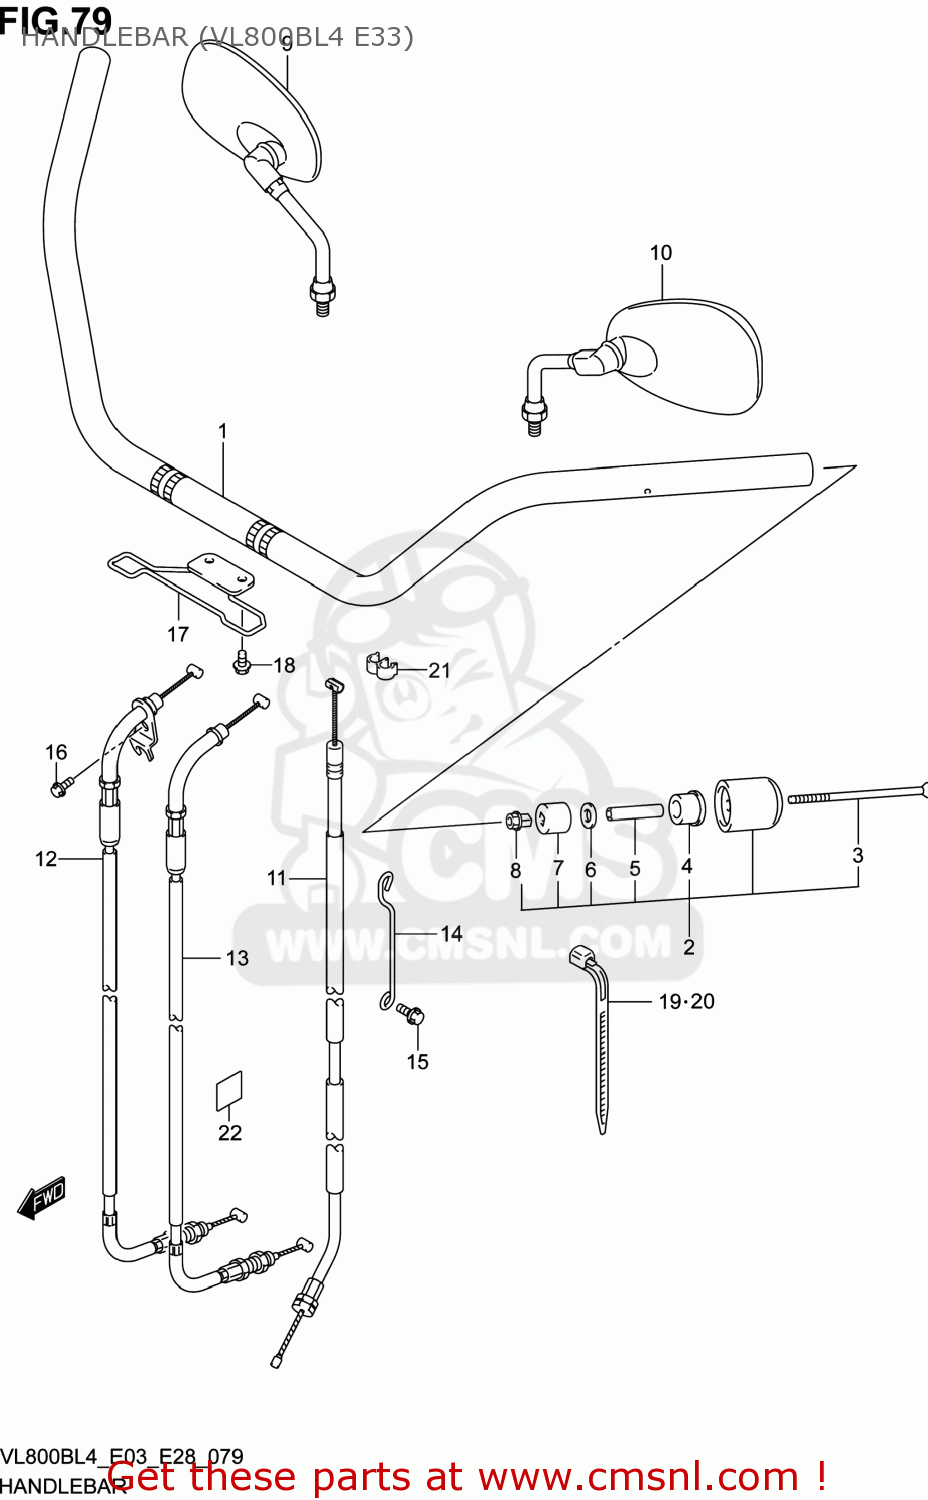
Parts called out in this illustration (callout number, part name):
1	HANDLEBAR
2	BALANCER SET,HANDLEBAR
3	SCREW(6X127)
4	EXPANDER,HANDLE BALANCER NO.2
5	SPACER,EXPANDER
6	WASHER(6.5X16X4)
7	EXPANDER,HANDLE BALANCER
8	NUT,HANDLE BALANCER
9	MIRROR ASSY,RR VIEW,R
10	MIRROR ASSY,RR VIEW,L
11	CABLE ASSY,CLUTCH
12	CABLE ASSY,THROTTLE NO.1
13	CABLE ASSY,THROTTLE NO.2
14	GUIDE,THROTTLE CABLE
15	BOLT
16	BOLT
17	GUIDE,CABLE
18	BOLT
19	CLAMP(L:190)
20	CLAMP(L:300)
21	CLIP
22	PROTECTOR
